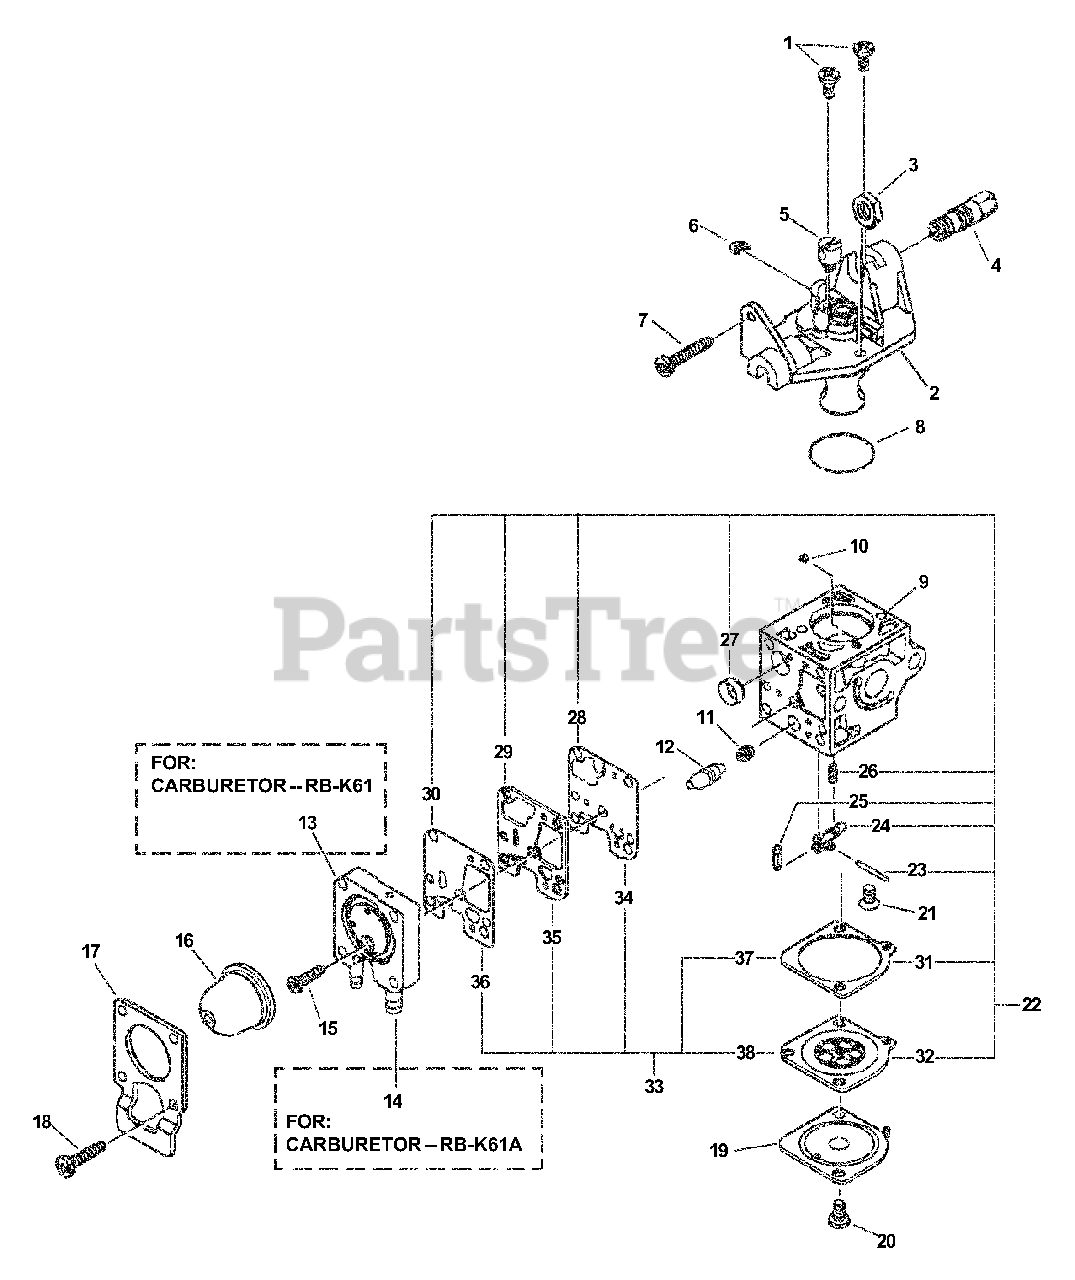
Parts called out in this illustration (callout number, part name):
2	ROTOR COVER ASSY
4	ADJUSTER, THROTTLE CABLE
7	SCREW, IDLE ADJUST
9	BODY, CARBURETOR
10	GUIDE, ROLLER
11	JET, MAIN
12	PLUG KIT
13	BASE, PURGE
14	BODY ASSY, PURGE
16	BULB, PURGE
17	RETAINER, PURGE BULB
18	SCREW, PURGE BULB RETAINER
19	COVER, METERING DIAPHRAGM
21	SCREW, METERING LEVER PIN
22	REBUILD KIT
23	PIN, METERING LEVER
24	LEVER, METERING
25	VALVE, INLET NEEDLE
26	SPRING, METERING LEVER
27	STRAINER
28	DIAPHRAGM, PUMP
29	GASKET, PUMP
31	GASKET, METERING
32	DIAPHRAGM, METERING
33	GASKET / DIAPHRAGM KIT
34	DIAPHRAGM, PUMP
35	GASKET, PUMP
37	GASKET, METERING
38	DIAPHRAGM, METERING
